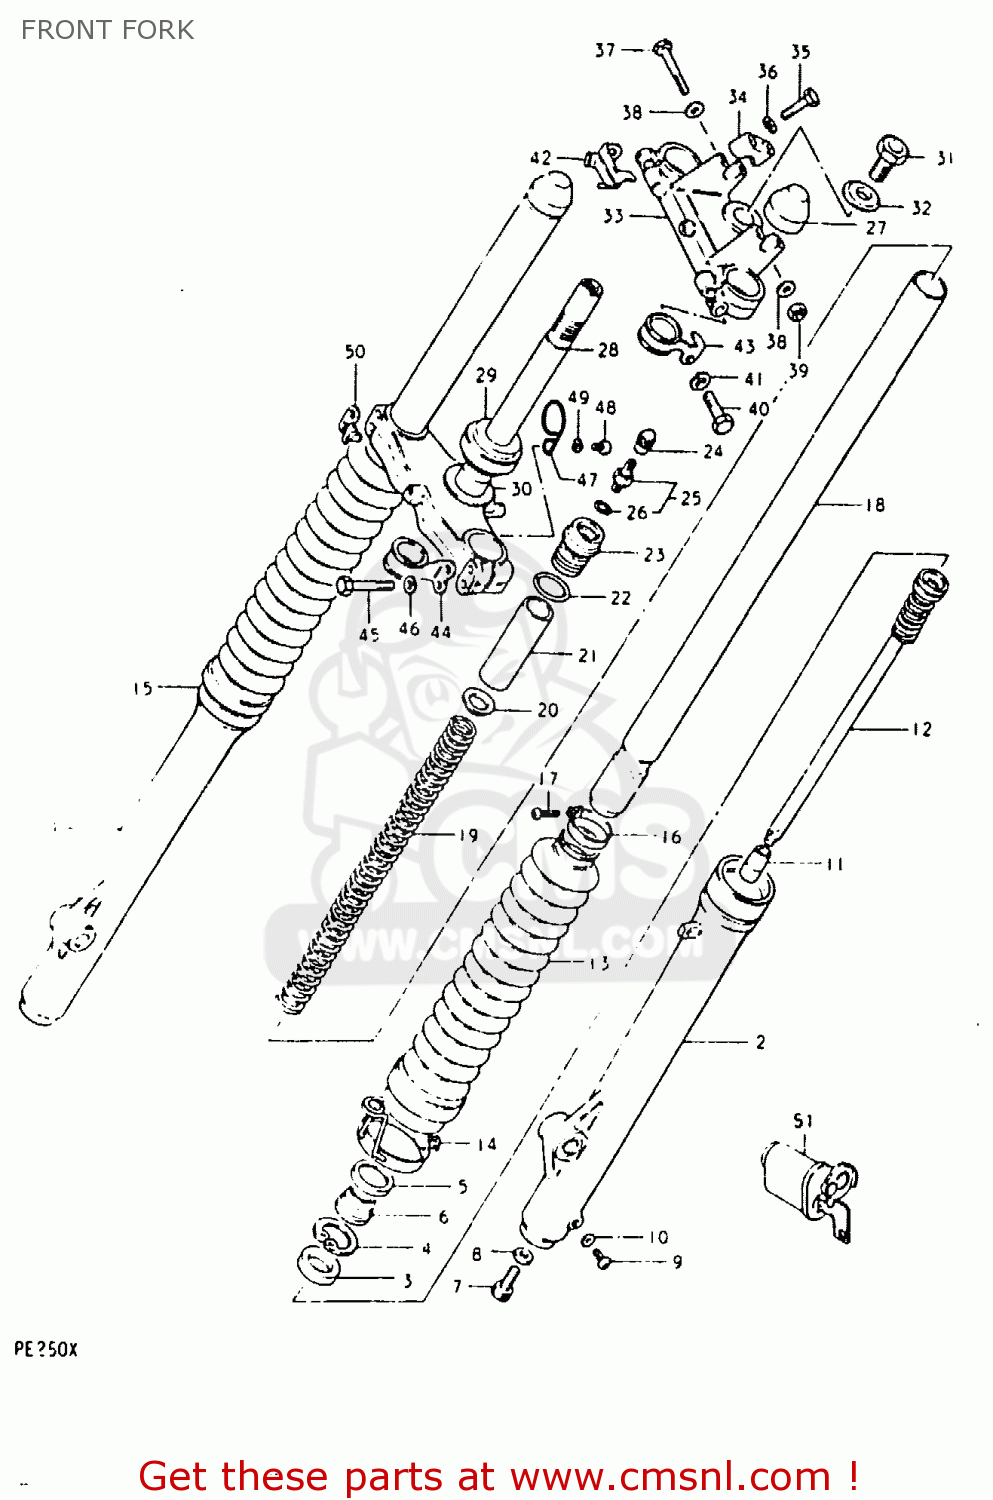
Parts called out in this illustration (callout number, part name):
1	TUBE,OUTER,RIGHT
2	TUBE,OUTER,LEFT
3	OIL SEAL,FRONT FORK
4	5
5	CASE,DUST SEAL
6	SEAL,DUST
7	BOLT,FORK CYLINDER(10X25)
8	GASKET (NAS)
9	SCREW
10	GASKET,DRAIN,PLUG (NAS)
11	PIECE,OIL LOCK
12	CYLINDER,FRONT FORK
13	BOOT
14	BAND,FORK COVER BOOT
15	BAND,FRONT FORK COVER
16	BAND,BOOT
17	SCREW
18	TUBE,FORK,INNER
19	SPRING
20	GUIDE,FRONT FORK SPRING C
21	COLLAR,SPRING
22	O RING
23	CAP,FORK INNER TUBE
24	CAP,VALVE
25	VALVE
26	O RING
27	CAP
28	STEM,STEERING
29	BEARING
30	WASHER,THRUST
31	BOLT
32	WASHER
33	HEAD,STEERING STEM
34	HOLDER,HANDLEBAR
35	BOLT
36	LOCK WASHER
37	BOLT 8X50
38	WASHER
39	NUT
40	BOLT
41	LOCK WASHER
42	BRACKET,TOOL FITTING,UPPER
43	GUIDE,CABLE
44	CLIP,CABLE
45	BOLT 8X45
46	LOCK WASHER
47	CLIP
48	SCREW
49	LOCK WASHER
50	BRACKET,TOOL FITTING,LOWER
